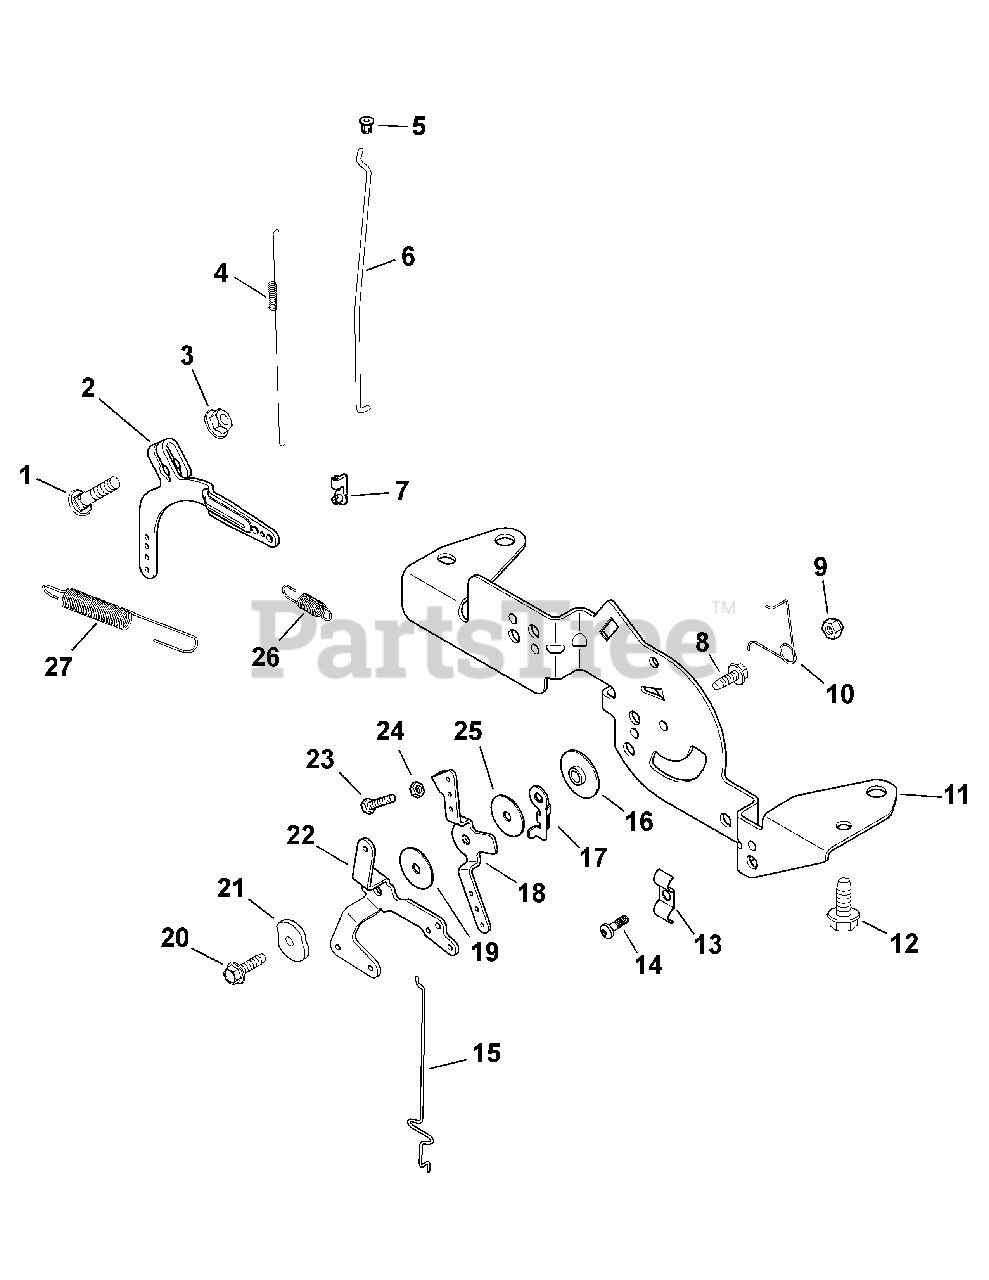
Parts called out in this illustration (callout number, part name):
1	Bolt, Carriage, M6 X 1.0 X 25
2	Lever, Governor
3	Nut, Flange, M6 x 1.0
4	Spring, Linkage
5	Bushing, Linkage Retainer
6	Linkage, Throttle
7	Bushing, Throttle Linkage
8	Screw, Flng. Thrd. Frmng, M5 x 0.8 x 16
9	Nut, Lock, M5 x 0.8
10	Spring, Choke Return
11	Bracket, Control
12	Screw, Flnge Thrd. Frmng M6 x 1.0 x 16
13	Clamp, Dual Conduit
14	Screw, Torx Hd. Ctsk, M5 x 0.8 x 16
15	Linkage, Choke
16	Spacer, Control Assembly
17	Lever, Throttle Actuator
18	Lever, Throttle Control
19	Washer, Flat, 5.5mm
20	Screw, Flng. Thrd. Frmng, M5 x 0.8 x 20
21	Washer, Spring, 1/4
22	Lever, Choke
23	Screw, Hex Cap, M4 x 0.7 x 25
24	Nut, M4 x 0.7
25	Washer, Flat, 5mm
26	Spring, Governor
27	Spring, Governor, Model i1046 ONLY
27	Spring, Governor, Model i1050 ONLY
